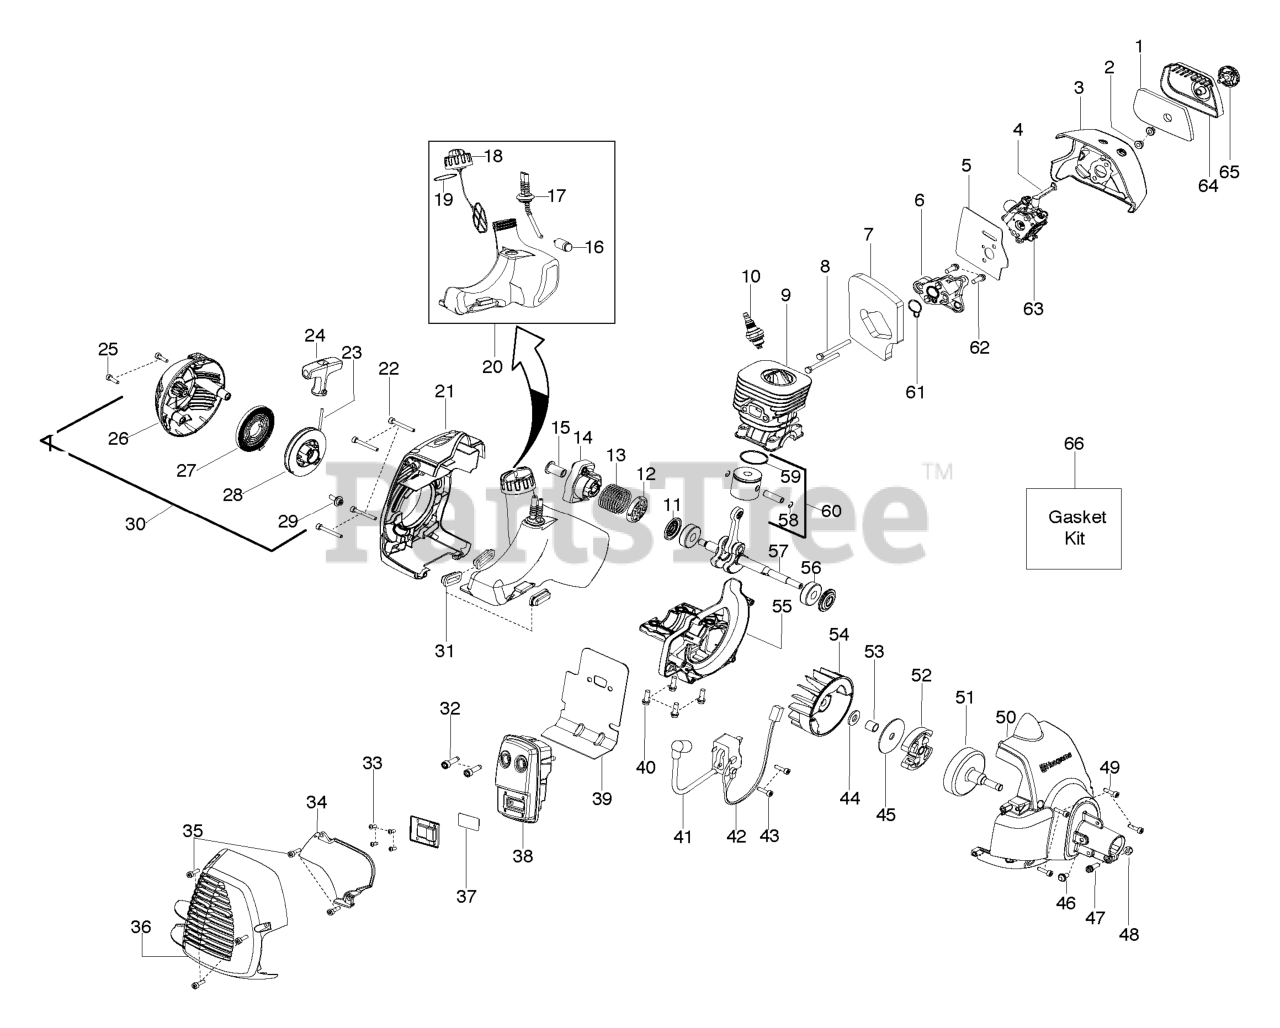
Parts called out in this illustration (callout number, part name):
1	FILTER AIRBOX
3	RP_AIR BOX
4	CHOKE LEVER
5	KIT GASKET CARB
6	CARB ADAPTOR
7	KIT GASKET 28CC TRIMMER
8	BOLT CARB ADAPTOR
9	CYLINDER
10	Plug-Spark (RCJ-8Y)
11	KIT SEAL CRANKSHAFT
12	WASHER STARTER
13	SPRING STARTER CUP
14	ASSY-STARTER CUP
15	COUPLING STARTER
16	FUEL PICK-UP ASSY
17	KIT FUEL LINE
18	ASSY-CAP W/RETAINER
19	O RING NITRILE
20	ASSY FUEL TANK
21	REAR SHROUD
24	STARTER HANDLE GRAY
25	SCREW M5-0.8X30MM
26	STARTER HOUSING
27	%KIT STARTER SPRING
28	KIT STARTER PULLEY
30	ASSY-STARTER HSG.
31	ISOLATOR FUEL TANK
32	BOLT MUFFLER
33	SCREW-10-16 X 1/2 HI-LO
34	SHIELD HEAT
35	SCREW M4 X 1.75 PT 16MM
36	MUFFLER GUARD
37	KIT SPARK ARRESTOR SCREEN
38	ASSY MUFFLER NC
39	GASKET PAPER METAL
40	SCREW-M5-0.8 X 25MM(TAP)
41	IGNITION MODULE MBU-7
42	ASSY MODULE LEAD WIRE
43	SCREW M4 X .70 TT 16MM
45	WASHER-CLUTCH
48	NUT HEX LOCK 10-24
49	SCREW M4 X .70 TT 16MM
50	FAN HSG ASSY
51	ASSY-CLUTCH DRUM
52	%KIT CLUTCH ASSY
53	SPACER FLYWHEEL
55	CRANKCASE CASTING
56	BEARING RADIAL BALL (6201)
57	KIT CRANKSHAFT ASSY
58	WRIST PIN RET.
59	RING PISTON
60	KIT PISTON 28CC TRIMMER
61	KIT GASKET 28CC TRIMMER
62	SCREW-M5-0.8 X 25MM(TAP)
63	CARBURETOR KIT
64	COVER-AIR BOX
65	KNOB ASSY AIRBOX COVER
66	KIT GASKET 28CC TRIMMER
